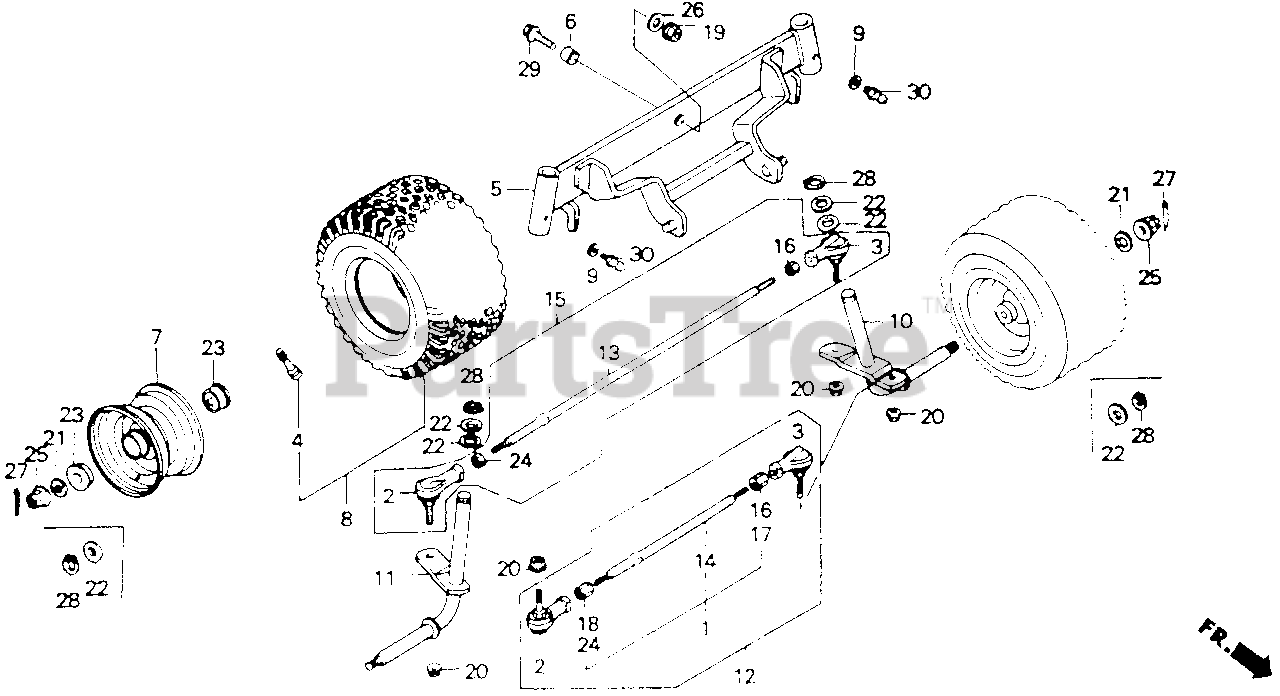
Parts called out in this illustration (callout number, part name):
1	TIE ROD SET B
2	JOINT, R. BALL
3	JOINT, L. BALL
4	VALVE, RIM
5	AXLE, FR. (NOT AVAILABLE)
6	COLLAR, FR. AXLE
8	TIRE, TURF (11X4.00-5)
9	COLLAR (6.5X11X3)
10	KNUCKLE, L. (NOT AVAILABLE)
11	KNUCKLE, R. (NOT AVAILABLE)
13	TIE ROD A (NOT AVAILABLE)
16	NUT, HEX. (8MM)
17	NUT, L. SLEEVE (8MM)
18	NUT, R. SLEEVE (8MM)
19	NUT, AXLE (10MM)
20	NUT, FLANGE (M8X1.25) (SELF-LOCK)
22	WASHER, THRUST (17MM)
23	BEARING, RADIAL BALL
24	NUT, HEX. (8MM)
26	WASHER, PLAIN (10MM)
28	CIRCLIP (OUTER) (17MM)
29	BOLT, FLANGE (10X35)
30	NIPPLE, GREASE (A.T6) (M6X1.0)
